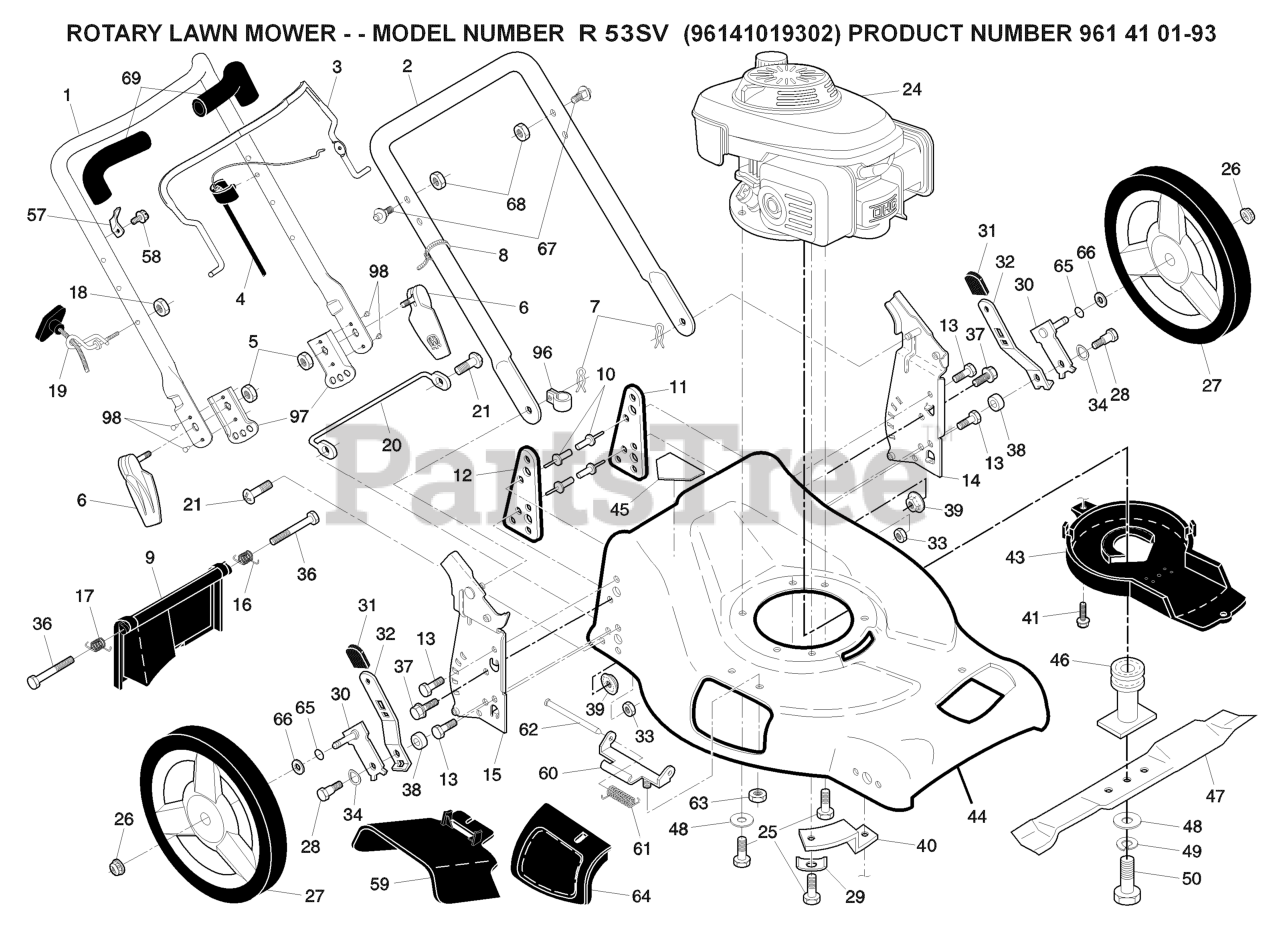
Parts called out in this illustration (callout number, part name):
1	HANDLE.ASM.UP.W/ADJ.BKT.21FGD
2	HANDLE.LOWER.GREY
3	BAIL CONTROL
4	CABLE.ASM.ZONE.CONTROL
5	NUT.HEX.FLANGE.1/4
6	ASM.QUICK.RELEASE
7	HAIRPIN COTTER
8	TIE GUIDE
9	REAR DOOR ASSEMBLY
10	RIVET BLIND
11	SUPPORT BRACKET LH
12	BRACKET.SUPRT.RH.21.FWGD
13	SCREW 14-20 X 5/8
14	RP BRACKET.ASM.HNDL/HW.LT.21.
15	BRACKET.ASM.HNDL/HW.RT.21.PNT
16	SPRING.REAR.DOOR.EZ.21.LT
17	SPRING.REAR.DOOR.EZ.21.RT
18	NUT
19	RB GUIDE.ROPE.STD.BLK.ZIN WSL
21	SCREW
25	BOLT 3/8-16X1-1/8
26	NUT.HEX.FLANGE.3/8-16.LOCKNUT
27	WHEEL ASSY
28	SHOULDER BOLT 5/16-18
29	WASHER.ENGINE.BZP
30	ARM.ASM.AXLE.REAR.5/9.POS.BZP
31	SELECTOR KNOB
32	SELECTOR SPRING
33	NUT.71038.31-18.HEX.NYLOCK
34	WASHER.CURVED.CYLINDRICAL
37	BOLT.FIN.HEX.5/16-18X3/4
38	SPACER.HEIGHT.ADJUSTER
39	NUT.FLANGE.5/16
40	BRACKET
41	SCREW.HEX.WSH
43	DEBRIS SHIELD
44	KIT.HSG.21.FGD.MC.ORG.CE SYM
45	DECAL.INTERNATIONL.CUTFINGER
46	Blade Adapter / Pulley
47	BLADE.21.PUSH
48	WASHER,HARDEN
49	LOCKWASHER
50	SCREW, HEX HD 3/8-24 X 1-3/8
57	BRACKET
59	DEFLECTOR.CLIPPIN.21.FGD
60	BRACKET.ASM.HINGE.21.FWGD.
61	SPRING.TORSION
62	ROD.HINGE.21
63	LOCKNUT.NYLOC.1/4-20
64	DOOR.MULCH.21.REAR.FWGD
65	O-RING..070X.487.NEOPRENE
66	WASHER.FLAT.1/2
67	STUD.QUICK.ADJUST
68	NUT.LOCK.5/16-18
69	GRIP.HANDLE.FOAM.WIDE.(1 SIDE)
96	CLIP.CABLE.BLK
97	BRACKET.ADJ.3POS.GREY
